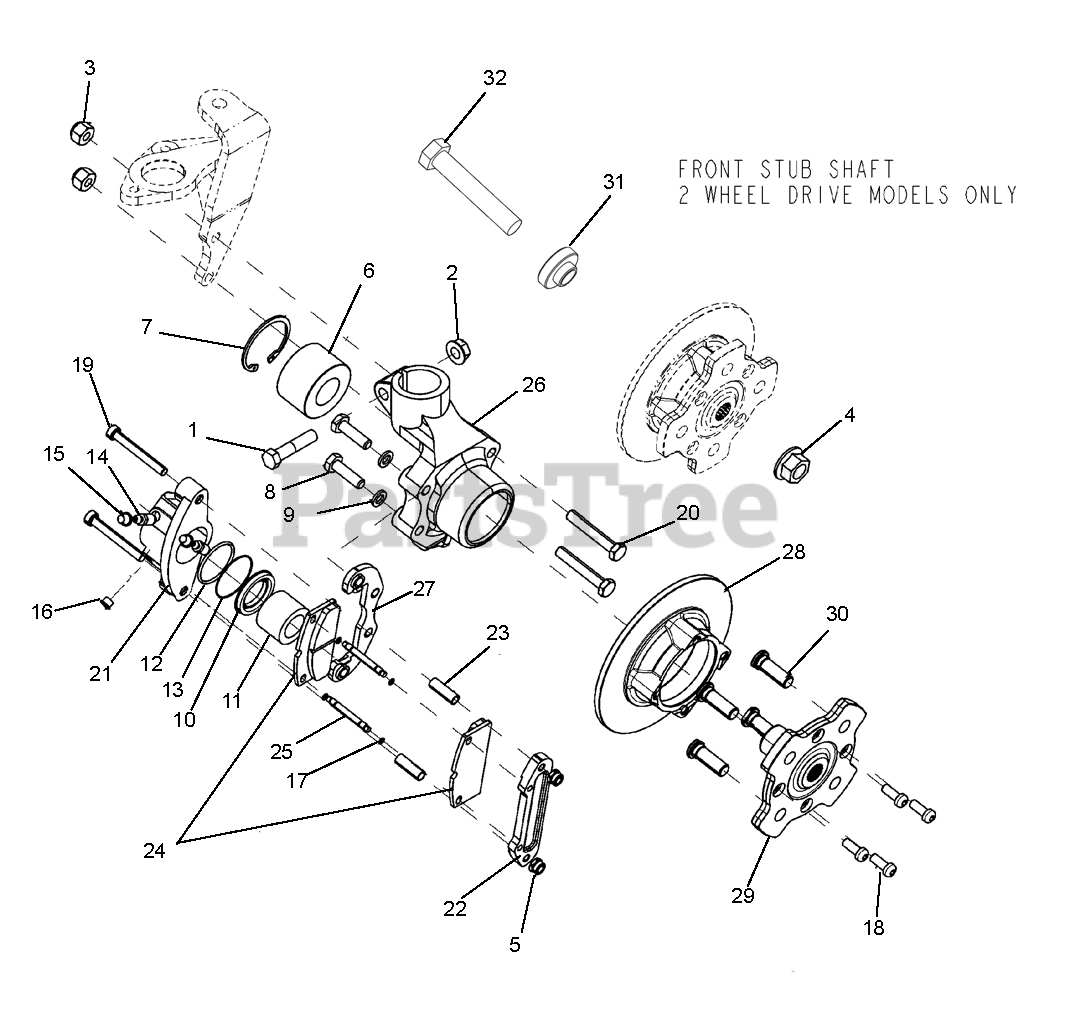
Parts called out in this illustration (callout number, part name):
1	BLT-HEX .38-16X2.00 GR8 YWZC
2	@NUT-LK-NYL .38-16 YWZC
3	NUT HEX NYLOCK M10X1.5 PLT
4	NUT HEX FLG T LCK M16X1.5 PLT
5	CMEX NUT M8
6	CMEX BALL BEARING 60,05X30X37
7	CMEX SEEGER
8	CMEX SCREW M 10 X 1.25 X 35
9	CMEX GROWER 10
10	CMEX DUST BOOT RING
11	CMEX CAP
12	CMEX SEALING RING
13	CMEX RUBBER DUST BOOT
14	CMEX BLEEDER SCREW
15	CMX BOOT
16	CMEX PLUG
17	CMEX DUST BOOT RING
18	CMEX SCREW M8 X 20
19	CMEX SCREW M8 X 65
20	CMEX HHS M10X1.5X50 PLT
21	CMEX CALIPER BODY
22	CMEX REACTION BRACKET
23	CMEX SPACER
24	BRAKE PAD KIT (COMP. 2 WHEELS)
25	CMEX PIN
26	CMEX WHEEL PIVOT
27	CMEX CALIPER CLAMPING PLATE
28	CMEX DISC BRAKE
29	CMEX FLANGE WITH STUDS
30	CMEX STUD
31	SPCR, STUB BOLT
32	BLT-HEX M16-1.5 X 90 8.8 YWZC
